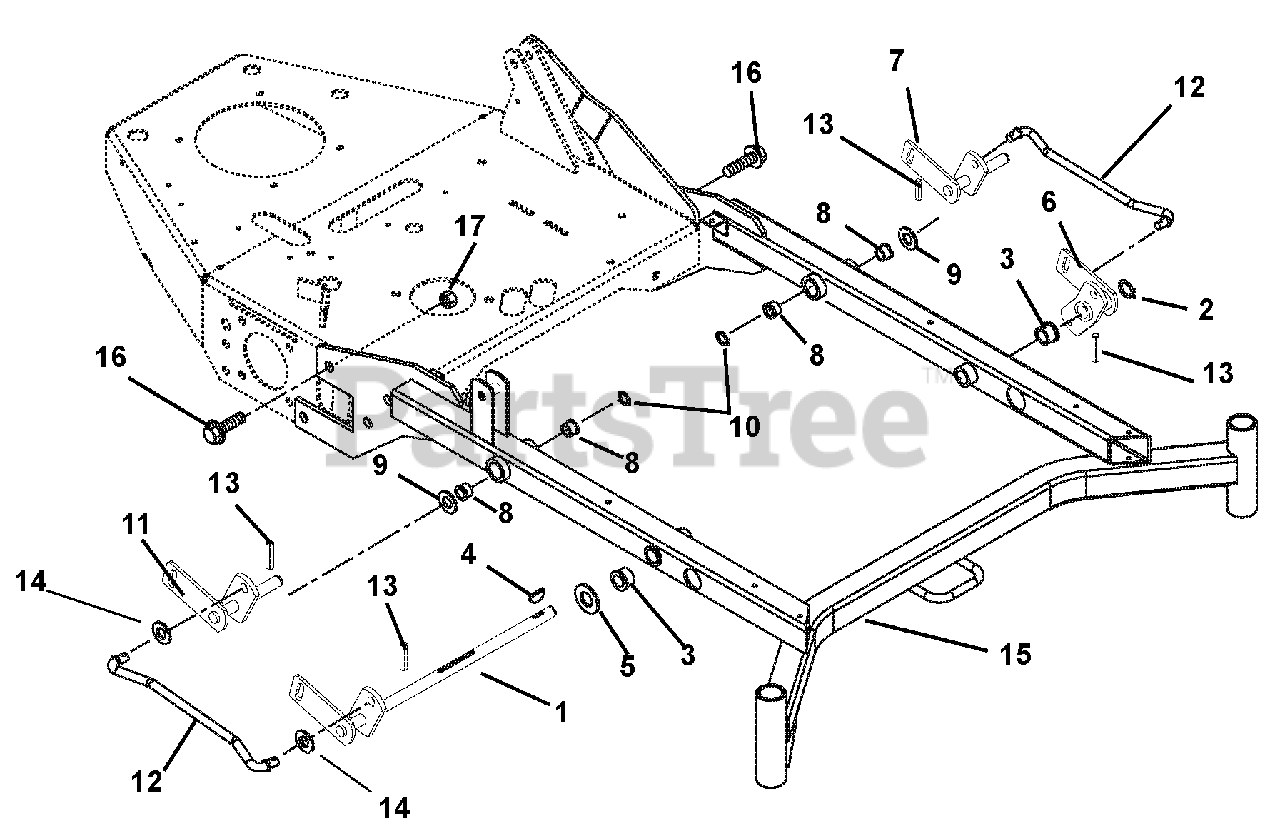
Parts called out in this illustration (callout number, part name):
1	Lift-Mower
2	Ring-Retaining-External 1.00 x .078
3	Bushing 1.00 x 1.25 x 1.937
4	Key-Woodruff .25 x 1.00
5	Washer-Flat-Steel- 1.062 x 2.0 x .134
6	Mower, Lift Arm
7	Weldment, Rear Lift Arm-Left Hand
8	Bushing-Flange-Nylon .762 x 1.0 x .580 x 1.48
9	Washer-Hardened-Steel .758 x 1.23 x .031
10	Ring-Retaining-External .689 x .077
11	Weldment, Rear Lift Arm- Right Hand
12	Rod, Lift Assist 19.35"
13	Pin-Roll .250 x 1.25
14	Washer-Flat-Steel .630 x 1.005 x .062
15	Weldment, Mower Frame 50/60
16	Bolt-Hex .62-11 x 1.50 Grade 5
17	Nut-Locking-Nylon .625-11
